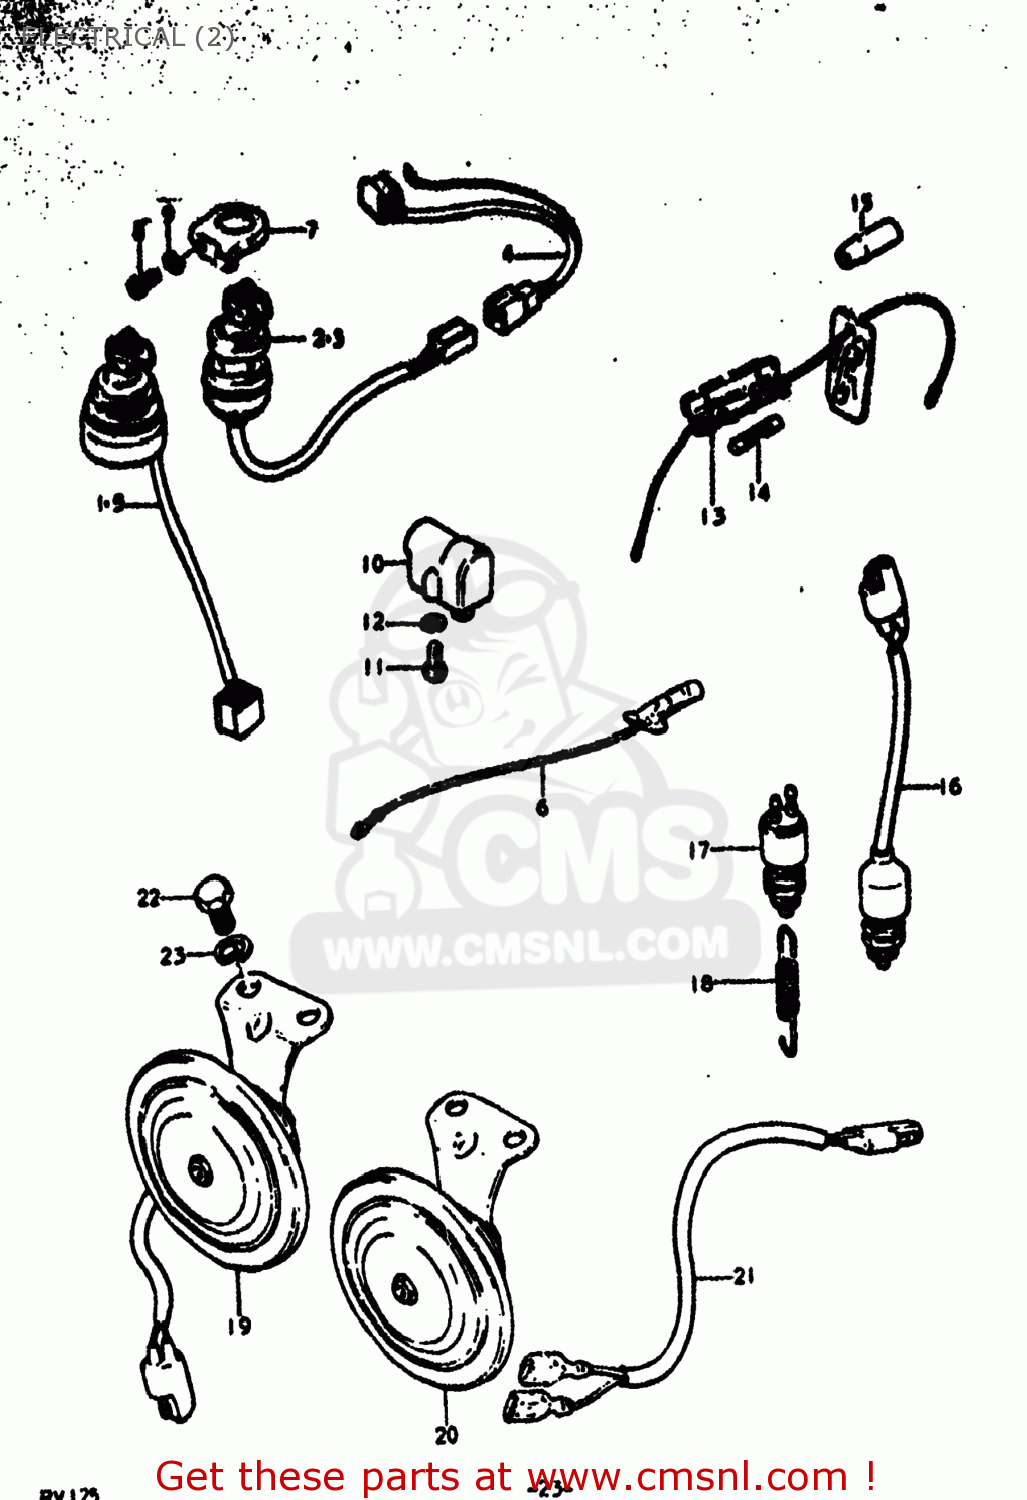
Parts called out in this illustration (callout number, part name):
1	SWITCH ASSEMBLY,IGNITION
2	SWITCH ASSEMBLY,IGNITION
3	SWITCH ASSEMBLY,IGNITION
5	SWITCH ASSEMBLY,IGNITION
6	WIRE,WIRING HARNESS LEAD
7	BRACKET,IGNITION SWITCH
8	SCREW 6X12
9	LOCK WASHER
10	LOCK ASSY,STEERING
11	Screw
12	LOCK WASHER
13	BOX ASSEMBLY,FUSE
14	FUSE(15A)
15	SEAL,DUST(10X17X45)
16	SWITCH ASSEMBLY,STOP LAMP
17	SWITCH ASSY,BRAKE LAMP
18	SPRING
19	HORN ASSEMBLY
20	HORN ASSEMBLY
21	WIRE
22	BOLT
23	LOCK WASHER
